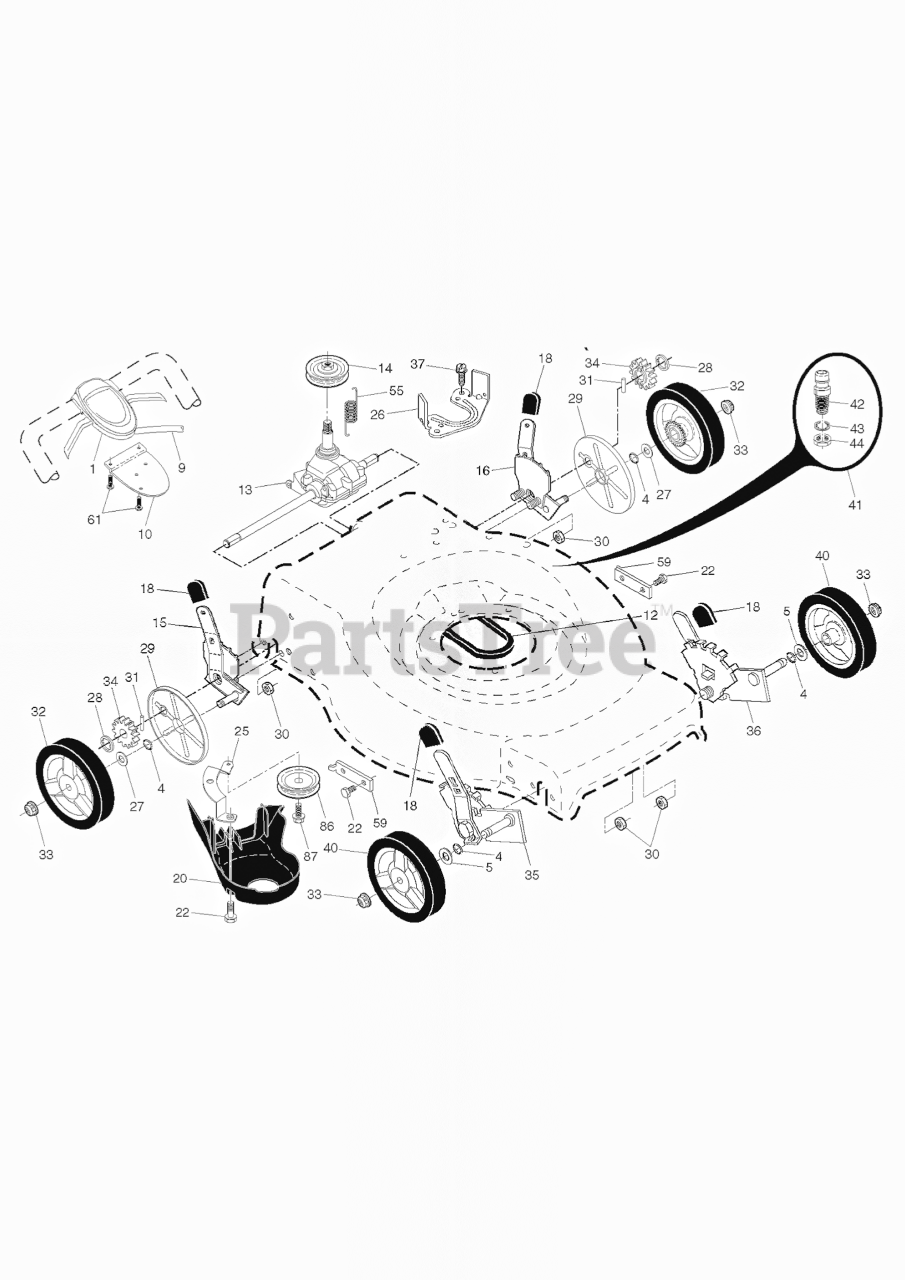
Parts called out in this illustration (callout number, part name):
1	CONTROL.DR.AW2.22+.BLK.GEN
4	O-RING..070X.487.NEOPRENE
5	WASHER.FLAT.1/2
10	BRACKET DUAL TRIGGER CONTROL
12	BELT V3L 35.42, CLUTCHING COVE
12	RP.BELT.DRIVE.RGD.SS.WALK
12	BELT.DRIVE.RWD+.SS.ZINC DUST
13	TRANMISSION.ASM.22+RGD.W/IDLER
13	TRANSMISSION.22+AWD.WALK.MOWER
14	PULLEY
14	PULLEY.DRIVE.SM.AWD/RWD
15	ADJUSTER.ASM.22+FGD.RF /AWD RT
16	ADJUSTER.ASM.22+FGD.LF /AWD LT
18	SELECTOR KNOB
20	COVER.REAR.DRIVE.22+2013
22	BOLT.5/16HEX.WHS.HD
25	BRACKET.DRIVE.COVER.RGD.
26	BRACKET.TRANS.BELTKEEP.21 RWD
26	BRACKET.TRANS.BELT.KEEPER.BZP
27	WASHER FLUT
28	E-RING 7/16 RE
29	COVER.DUST.WHEEL.INNER.WALK
30	NUT.HEX.FLANGE.1/4
31	PAWL, DRIVE
32	WHEEL.8X1.75.3SPK.RAD3.GREY
33	NUT.HEX.FLANGE.3/8-16.LO(3 2)
34	PINIION.14.TOOTH.RGD
35	ADJUSTER.ASM.9POS.LW.RL/RGD.FR
35	ADJUSTER.ASM.9POS.LW.RGD.FR
36	ADJUSTER.ASM.LH FRONT/RH REAR
36	ADJUSTER.ASM.9POS.LW.RR/RGD.
40	WHEEL & TIRES ASSY, FRONT
41	KIT.WASH-OUT.PORT.ZINC.WALK
42	WASHOUT.PORT.ZINC.RGD.22+
43	WASHER.LOCK.INTERNAL.TOOTH
44	LOCKNUT.HEX.WITH.O-RING
55	SPRING.RETURN.AUTO.
59	BRACKET.SUPPORT.22+RWGD.BZP
61	SCREW, PHILLIPS HEAD 10 X 5/8
86	PULLEY.RWD.IDLER.DBL SEAL
